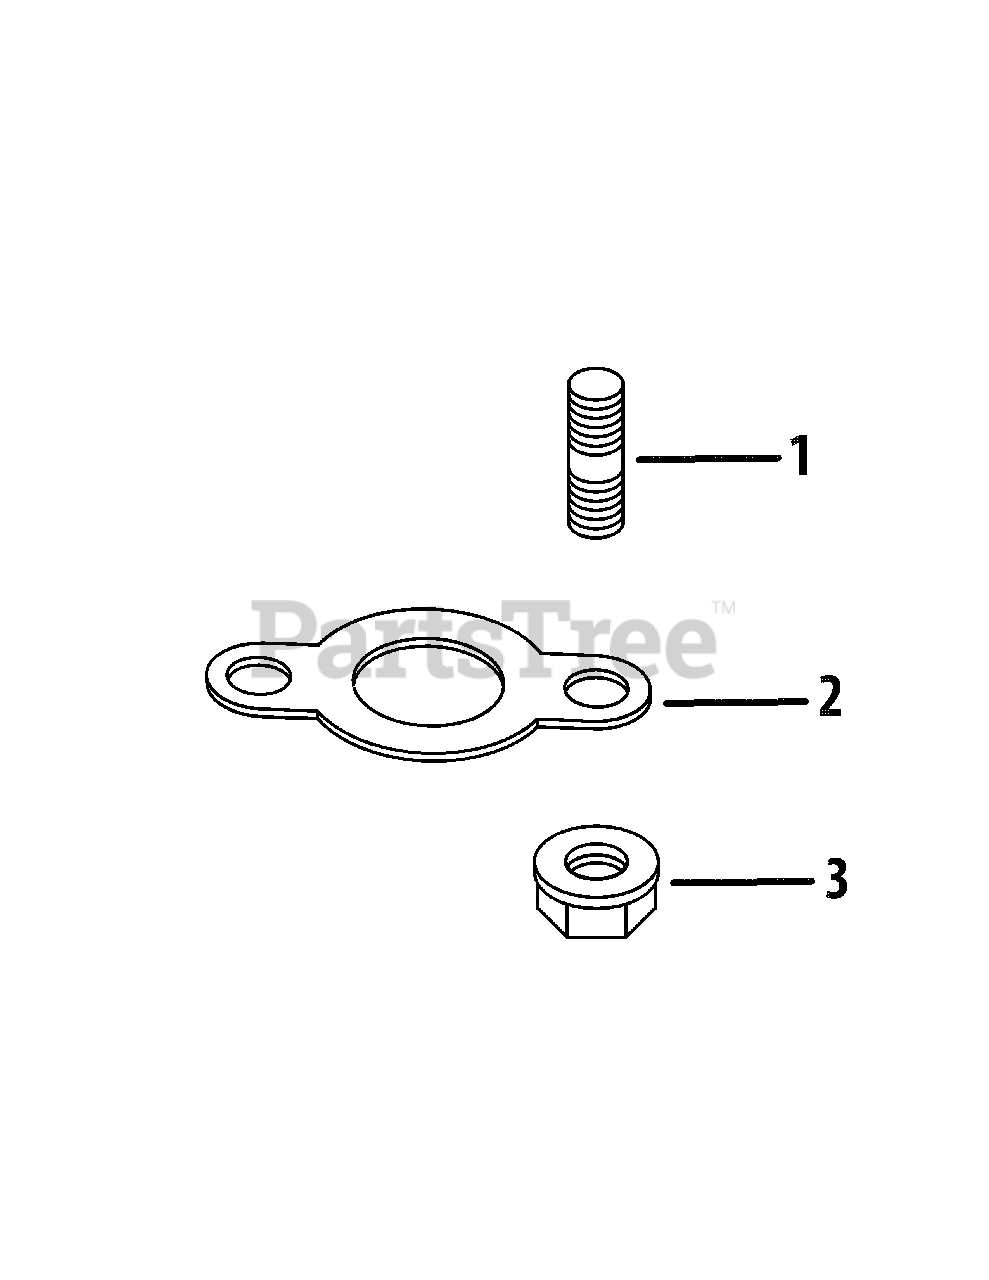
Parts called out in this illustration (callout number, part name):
1	Stud, M8X1.25X33
2	Gasket, Exhaust
3	Nut, Flg M8X1.25
